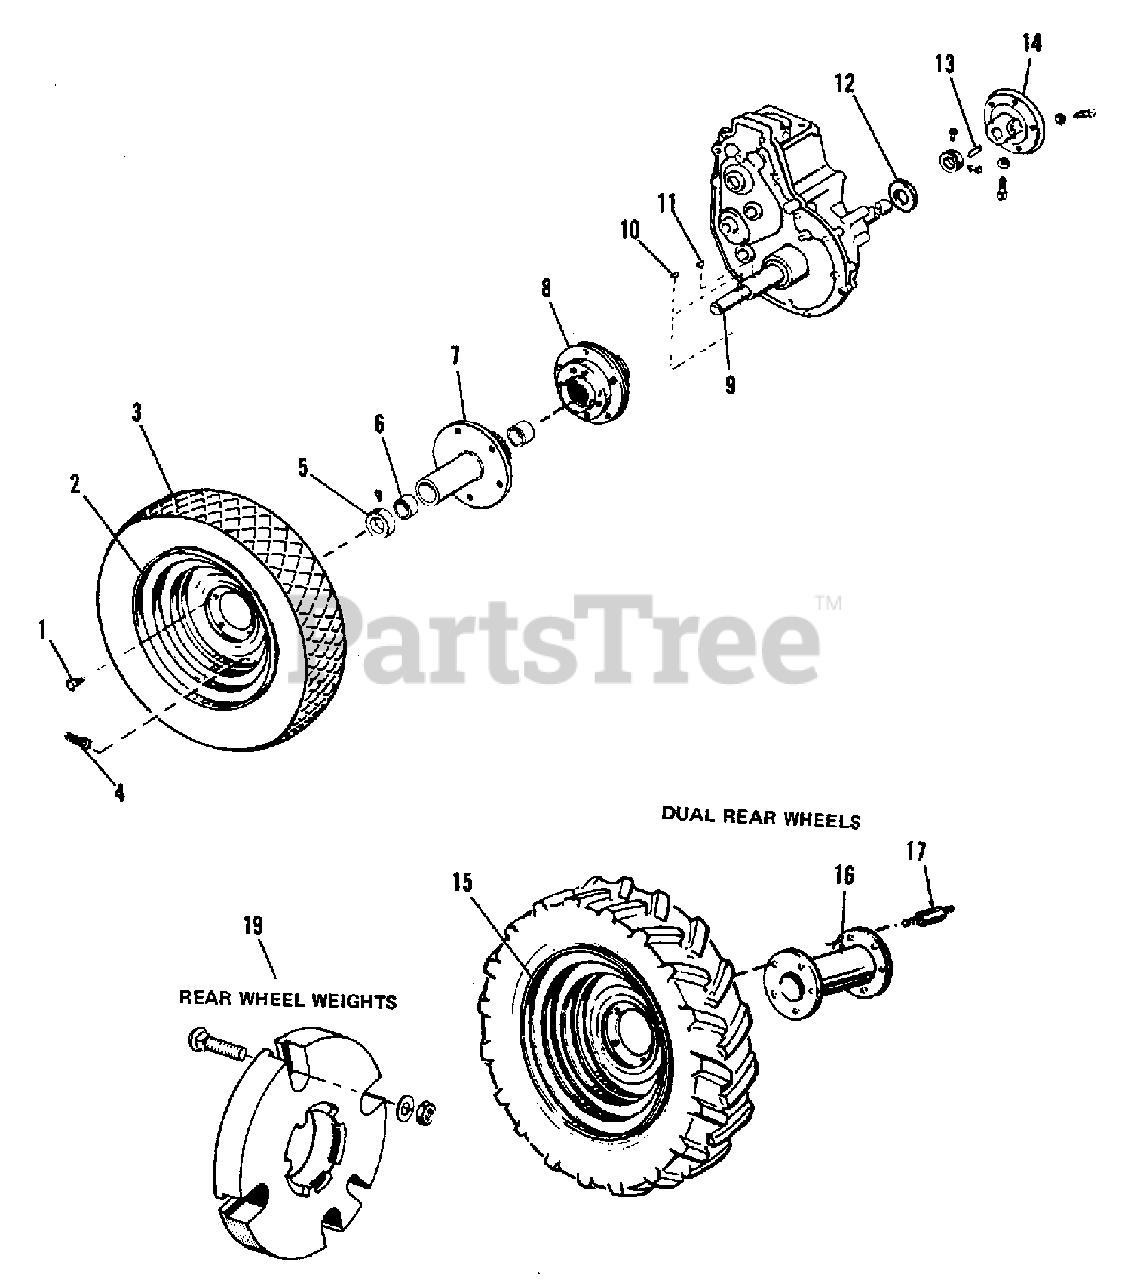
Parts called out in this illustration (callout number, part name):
1	BOLT, Rear Wheel
2	WHEEL, Rear (F/23 x 8. 50-12 Tires)
2	WHEEL, Rear (F23 x 10. 50-12 Tires)
3	TIRE (Obtain Locally)
3	TUBE, Tire (F/23 x 8. 50-12 Tires)
3	TUBE, Tire (F23 x 10. 50-12 Tires)
4	VALVE ASSEMBLY, Stem & Cap
5	COLLAR, Axle
5	SETSCREW, Square Head, Cup Pt., 5/16 NC x 3/8, Gr.8
7	HUB ASSEMBLY, R.H. (Includes Item 6)
8	DIFFERENTIAL ASSEMBLY, (See DRIVE TRAIN)
9	AXLE, Rear
10	KEY, Hi-Pro
11	KEY, Drive
14	HUB ASSEMBLY, L.H.
14	SETSCREW, Square Head, Cup Pt., 3/8NC x 1-1/2, GR8
14	SETSCREW, Square Head, Cup Pt., 3/8NC x 1, GR8
14	NUT, Jam, 3/8NC
15	WHEEL, Dual Rear
16	ADAPTER, Rear Wheel
17	STUD, Adapter
17	NUT, 7/16NF
17	LOCKWASHER, 7/16
18	CAP, Chrome Hub
19	WEIGHT, Rear Wheel (See MACHINERY)
19	BOLT, Wheel Weight
19	BOLT. 1/2NC x 2-1/2
19	WASHER, 1/2
19	NUT, 1/2NC
